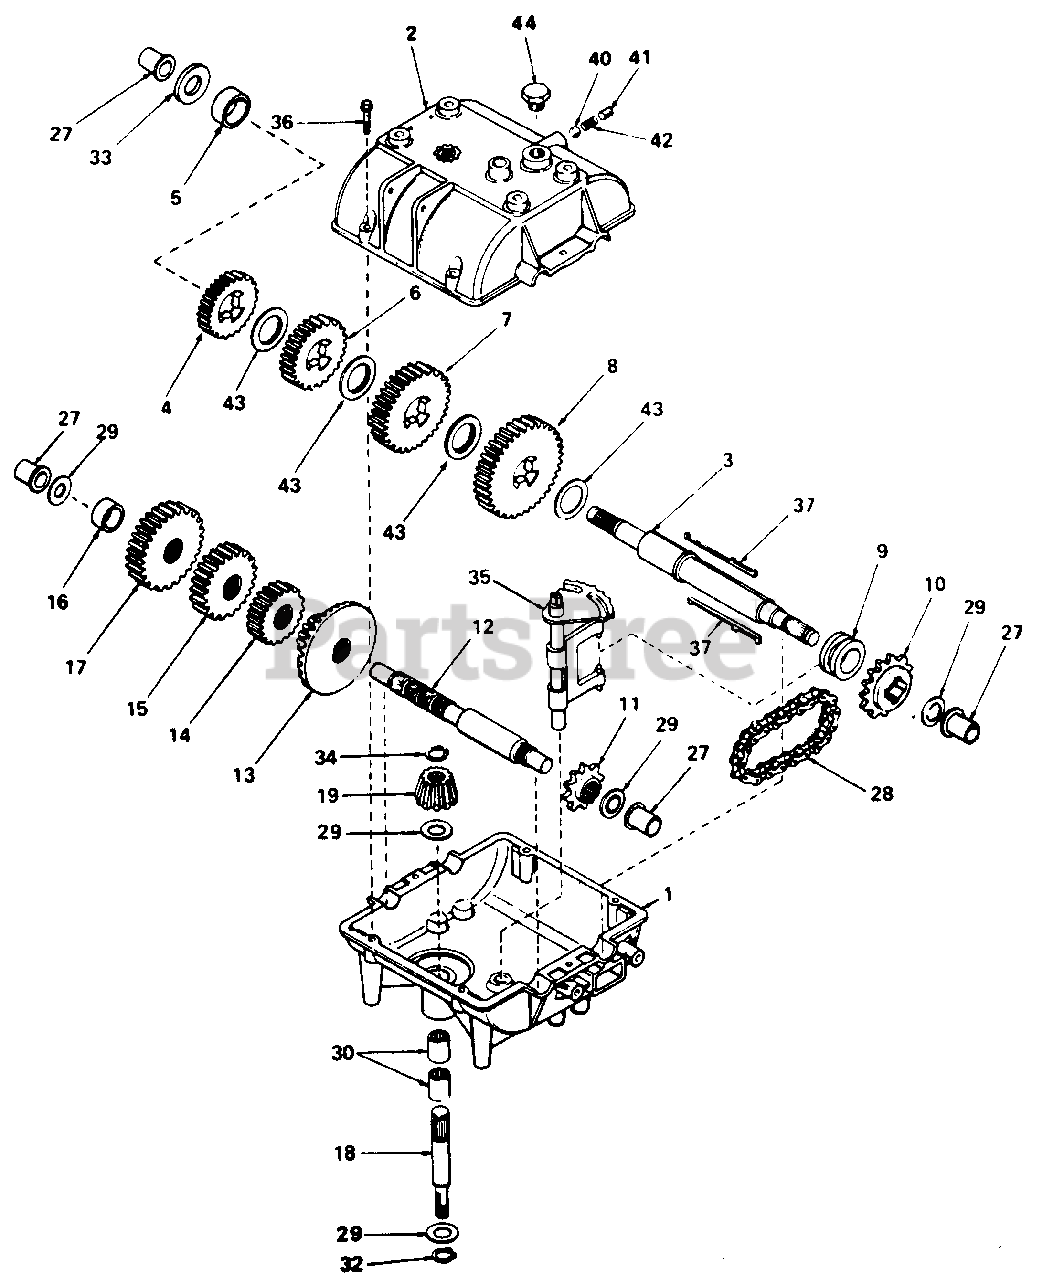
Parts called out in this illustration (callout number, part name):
1	Case, Transmission
2	Cover, Transmission
3	Shaft, Output
4	Gear, Spur (20 Teeth)
5	Gear, Spur (22 Teeth)
6	Gear, Spur (25 Teeth)
7	Gear, Spur (30 Teeth)
8	Gear, Spur (35 Teeth)
9	Collar, Shift
10	Sprocket (18 Teeth)
11	Sprocket (9 Teeth)
12	Shaft, Counter
13	Gear, Bevel (42 Tooth & 15 Tooth Spur Gear)
14	Gear, Spur (20 Teeth)
15	Gear,.Spur (25 Teeth)
16	Gear, Spur (28 Teeth)
17	Gear, Spur (30 Teeth)
18	Shaft, Input
19	Bevel Pinion, Input
27	Bushing, Flanged
28	Chain, Roller (No. 41 Chain, 22 Links)
29	Race, Thrust
30	Bearing, Needle
32	Ring, Retaining
33	Washer
34	Ring, Retaining
35	Rod and Fork Ass'y., Shift
36	Screw, Hex Hd. Taptite, 1/4-20 x 1 1/4
40	Ball, Steel, 5/16"
41	Screw, Set, 3/8-16 x 3/8
42	Spring
43	Washer, Thrust
